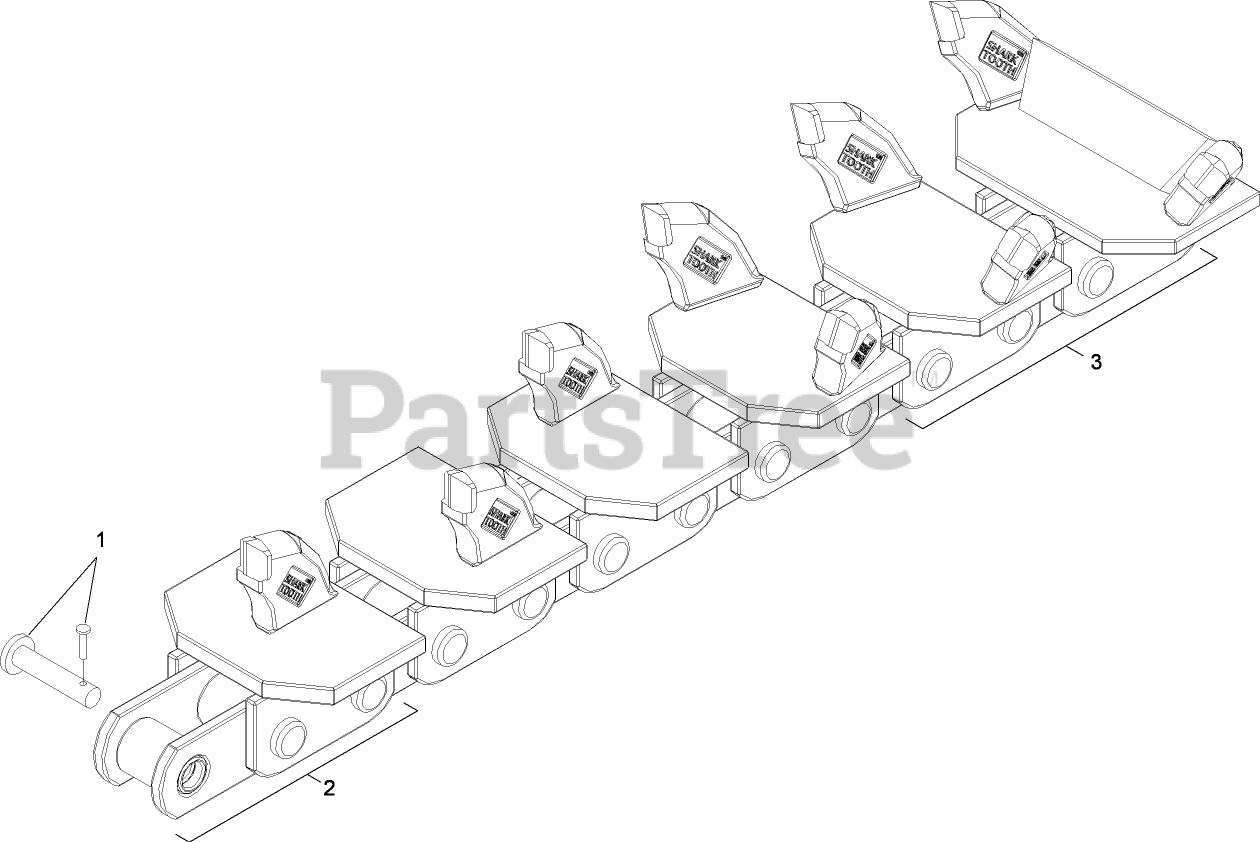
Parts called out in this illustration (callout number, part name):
1	PIN AND KEY KIT
2	STATION-REPAIR, SINGLE
3	STATION-REPAIR, 6 INCH
